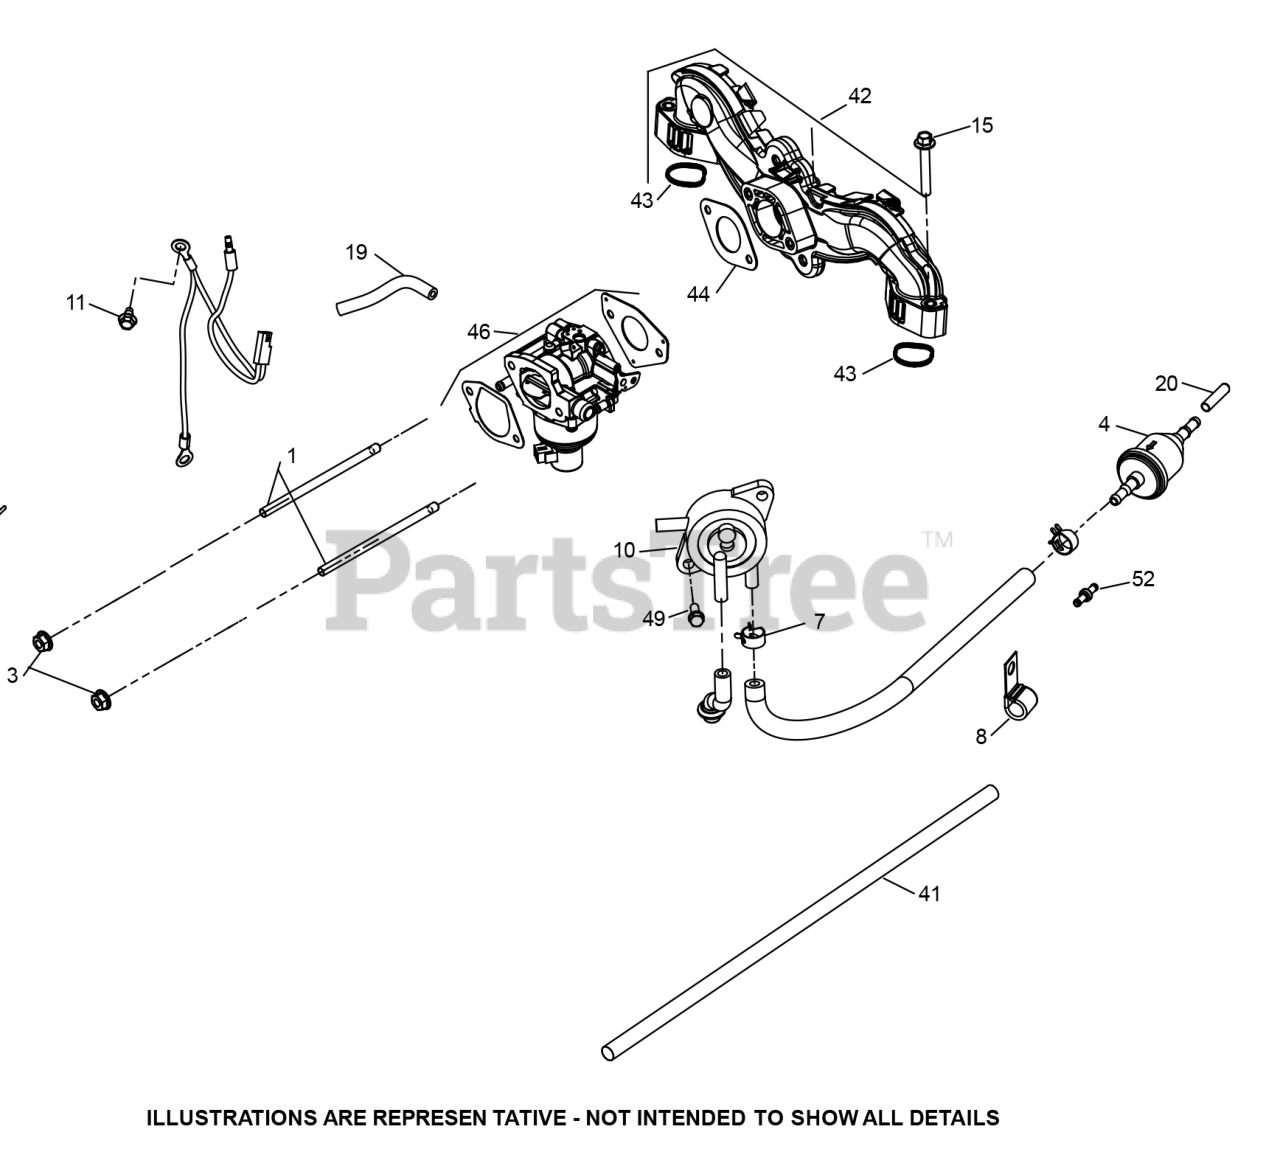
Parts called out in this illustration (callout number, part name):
1	CARB MOUNTING STUD
3	HEX FLANGE NUT
8	CLIP
15	HEX SCREW FLANGE
19	EVAPORATIVE HOSE
41	SLEEVE-ANTI ABRASION
42	INTAKE MANIFOLD W/GASKETS
43	O-RING, INTAKE PORT
44	GASKET, CARBURETOR (PIM, CV)
46	CARBURETOR KIT NIKKI
49	HEX HEAD SCREW
